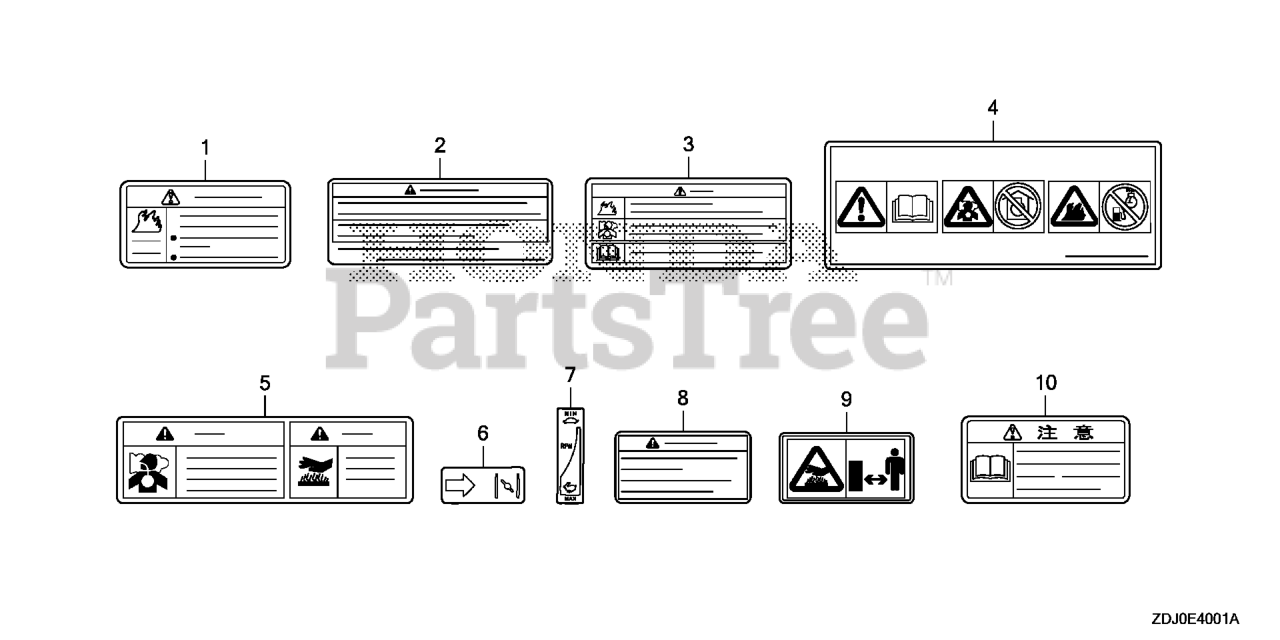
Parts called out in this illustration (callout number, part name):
2	MARK, OPER CAUTION
4	MARK, OPER CAUTION
6	MARK, CHOKE INDICATION
8	MARK, EX. CAUTION (FRENCH)
9	MARK, EX. CAUTION (PICTOGRAPH)
